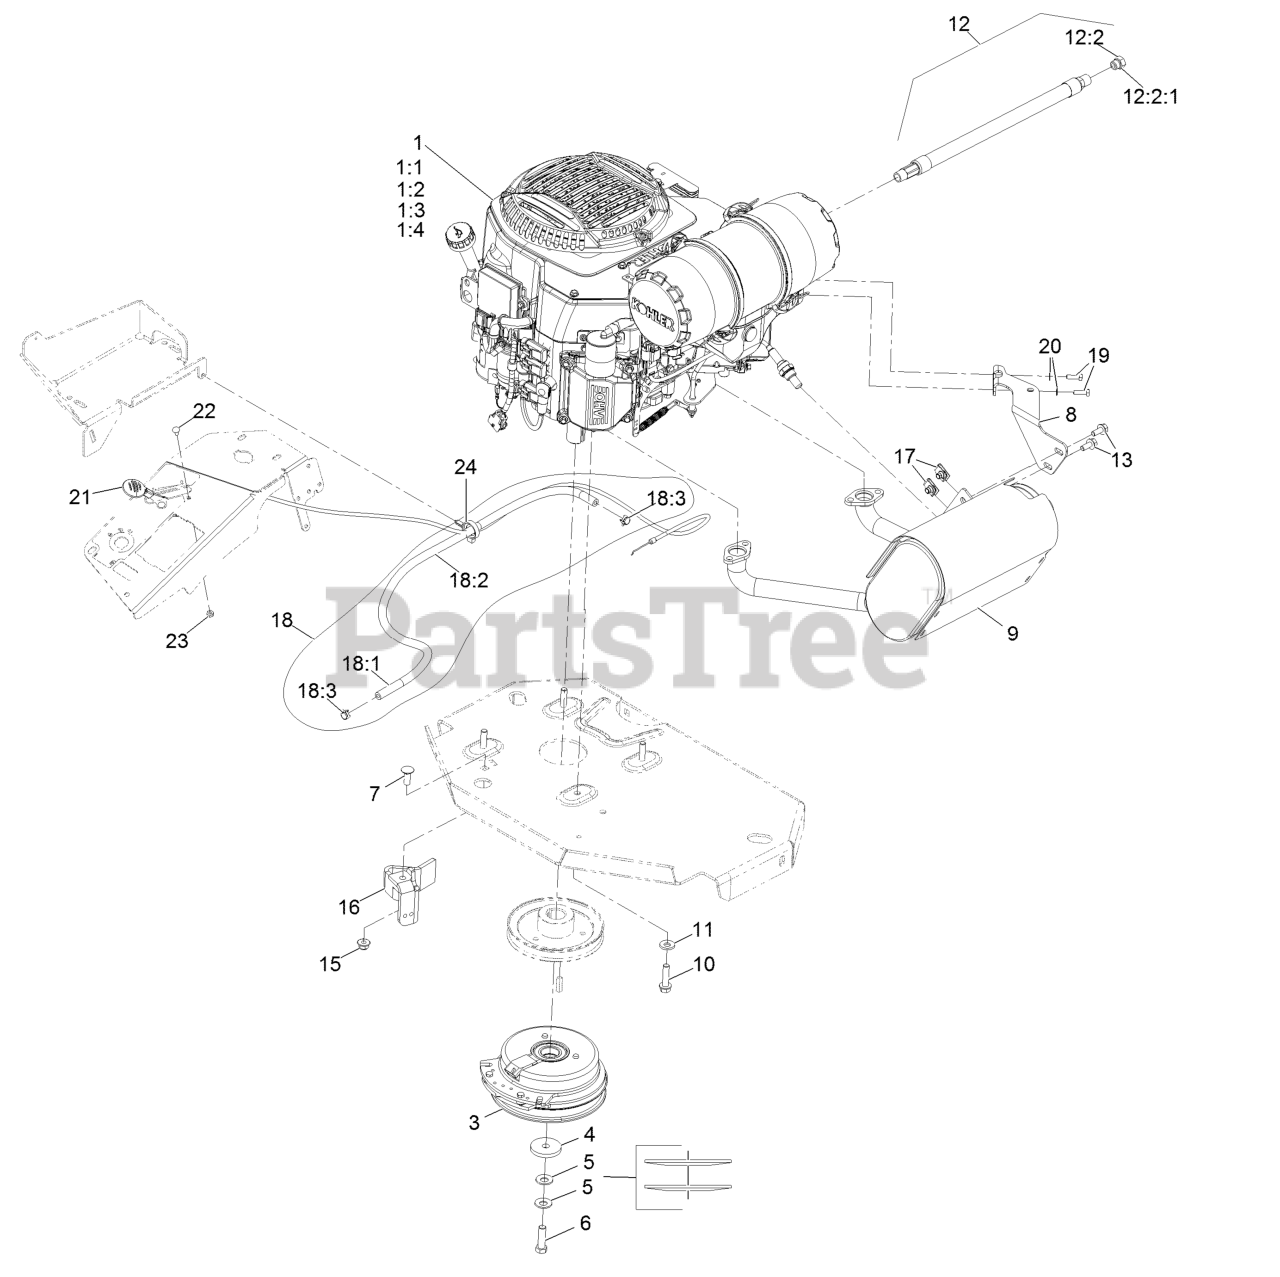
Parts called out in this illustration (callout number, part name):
1:1	Kohler 52 050 02-S Engine Oil Filter
1:2	Kohler 25 083 01-S Engine Air Filter
1:3	Kohler 25 083 04-S Safety Filter
1:4	Kohler 25 050 42-S Fuel Filter
3	Clutch Kit
4	Washer-Clutch
5	Washer-Spring Disc 7/16
6	Screw-HH 7/16-20 X 1 1/2 W/Loctite
7	Bolt-Carriage 3/8-16 X 1
8	Muffler Bracket Kit
9	Muffler Kit
10	Screw-HWH 3/8-16 X 1 1/2 Taptite
11	Washer-Spring Disc 3/8
12	Oil Drain Hose ASM
12:2	Plug-W/O-Ring
12:2:1	O-Ring
13	Screw-HH Flg 5/16-18 X 3/4
15	Nut-Nyloc 3/8-16 Flg
16	Clutch-Anchor
18	Fuel Line ASM
18:1	Hose-Fuel Line 38 1/4"
18:2	Sleeve-Thermal
18:3	Clamp-Hose
19	Screw-HH M6-1 X 20Mm W/Patch
20	Washer-Spring Disc 1/4
21	ASM,Throttle Cable
22	Bolt-Carriage #10-24 X 1/2
23	Nut-Nyloc #10-24
24	Clamp-Hose
